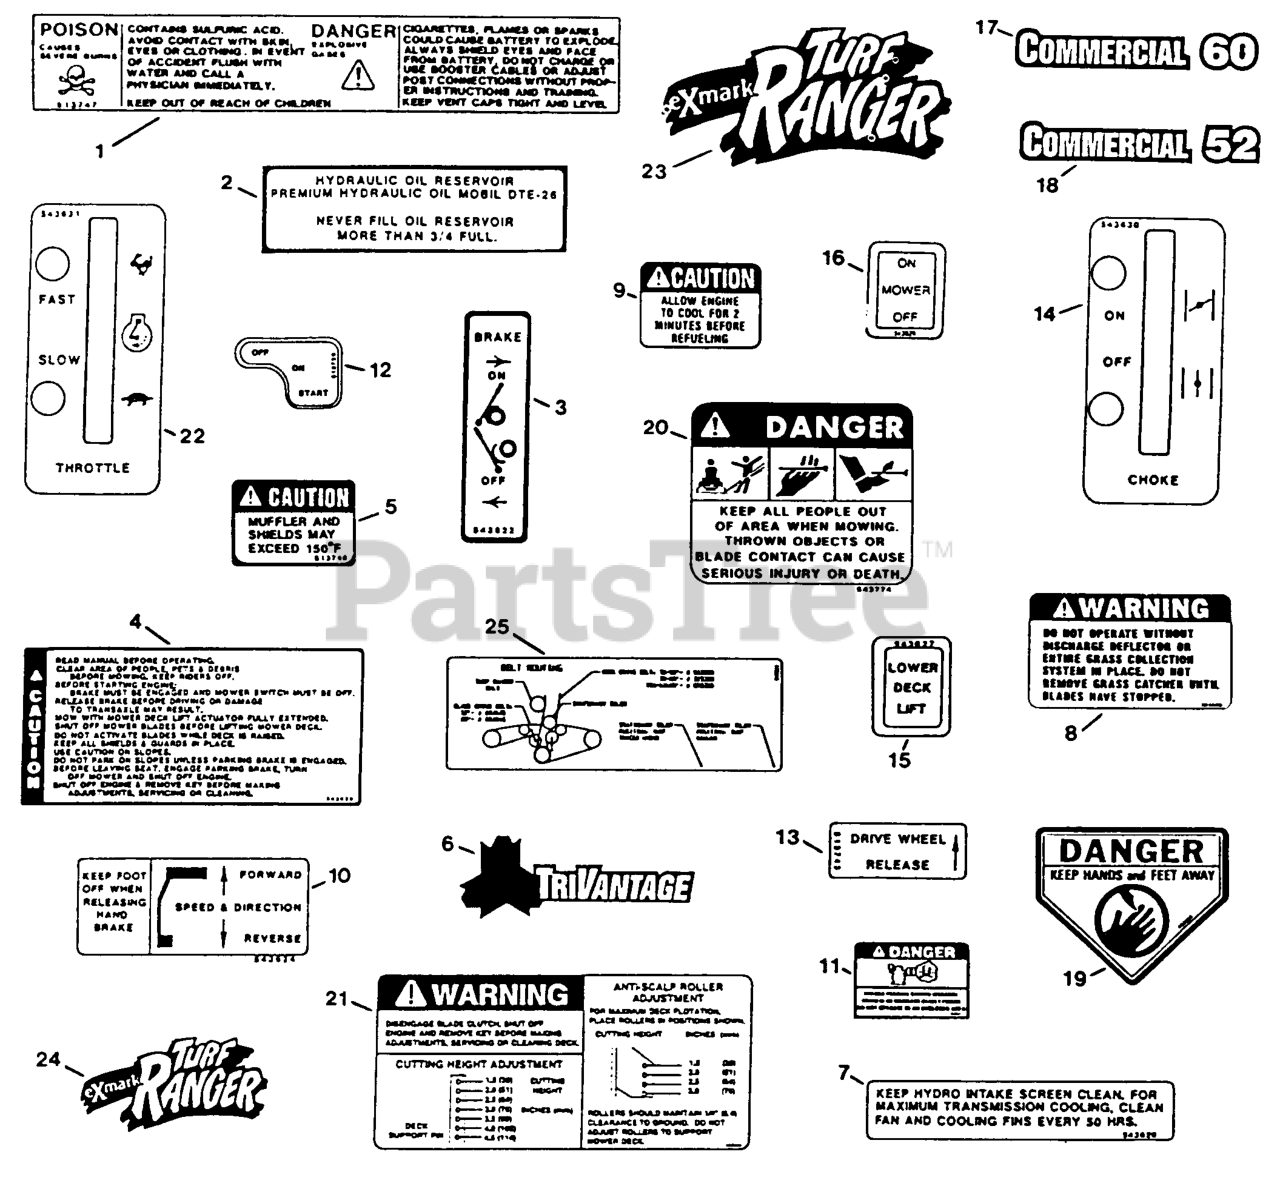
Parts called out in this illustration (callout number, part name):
1	DECAL-BATTERY
7	DECAL,INTAKE
8	DECAL-WARNING, DISCHARGE
10	DECAL,FOOT PEDAL
15	DECAL-DECK LIFT
16	DECAL-MOWER SWITCH
17	DECAL,COMMERCIAL 60
18	DECAL,COMMERCIAL 52
19	DECAL-DANGER
20	DECAL-DANGER
23	DECAL,SWASH RANGER
